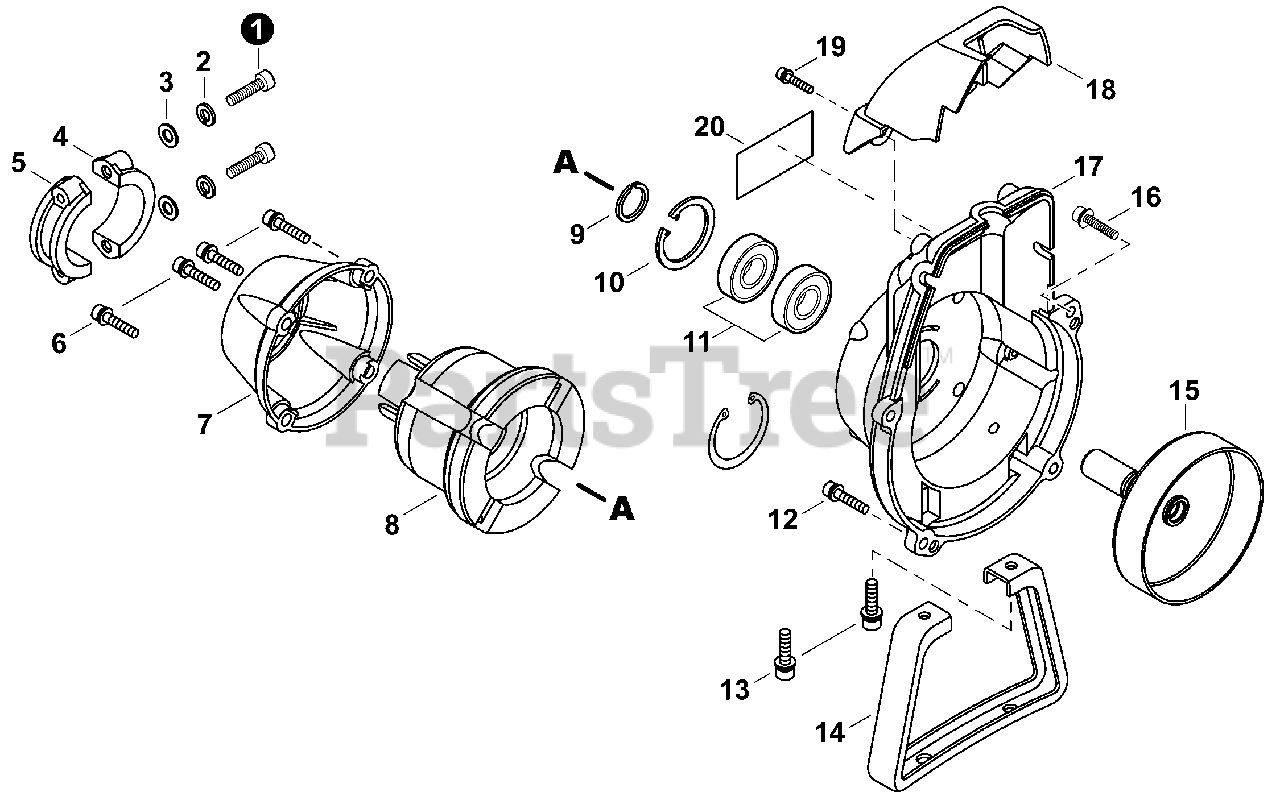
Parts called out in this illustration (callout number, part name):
1	BOLT 5×25
2	WASHER, SPRING 5
3	WASHER, FLAT 5.5×10×0.8
4	CLAMP - B
5	CLAMP - A
6	BOLT 5×20
7	CAP, CUSHION
8	CUSHION, AV
9	RING, SNAP
10	RING, SNAP Ø32
11	BEARING, BALL 6002 DDU
12	BOLT 5×20
13	BOLT 5×16
14	STAND
15	DRUM, CLUTCH
16	BOLT M5×30
17	COVER, FAN
18	GUARD, TOP
19	BOLT M4×16
20	LABEL - MODEL B45LA
